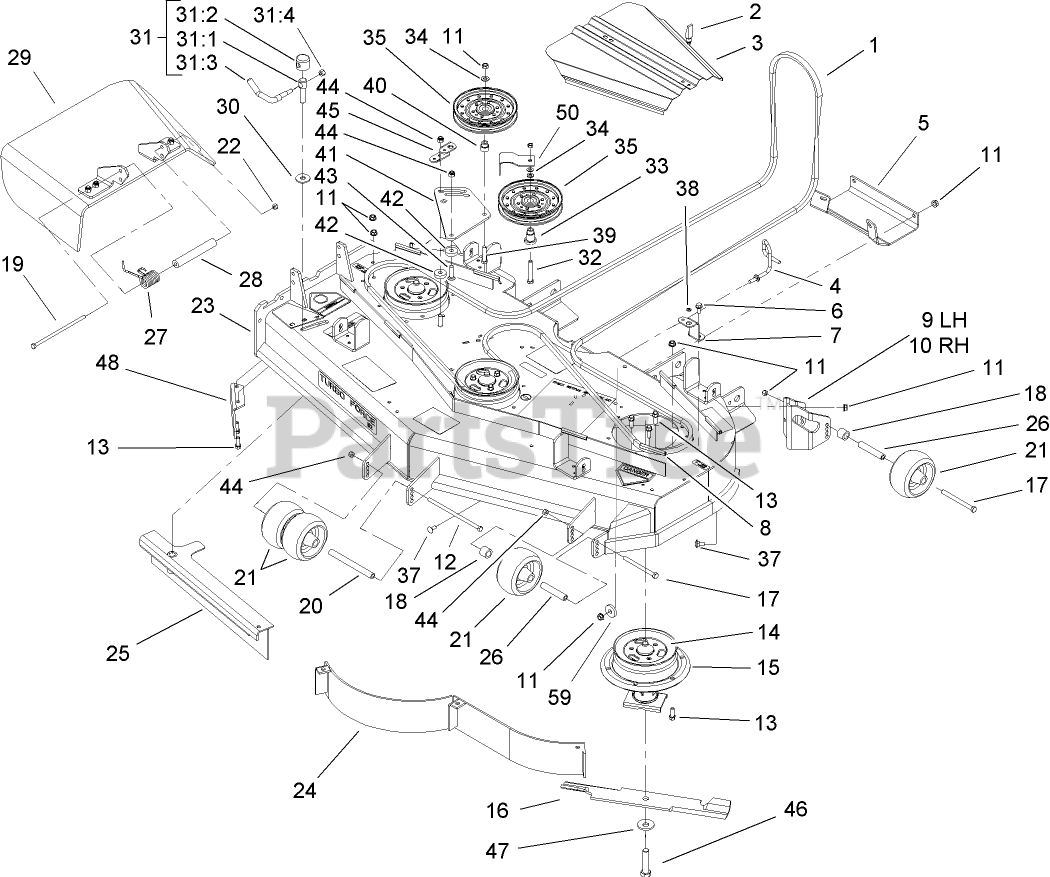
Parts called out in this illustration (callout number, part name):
2	LATCH-SWELL
3	Cover-Belt
4	GUIDE-BELT
5	Plate-Skid
6	SCREW-HWHTF
7	Bracket-Cover
8	STRIP-SEAL
9	MOUNT-WHEEL, LH
10	MOUNT-WHEEL, RH
11	NUT-HHF, WHIZ
12	SCREW-HH
13	SCREW-HWH
14	Pulley
15	Spindle ASM
16	BLADE-18IN, HI FLOW
17	SCREW-HH
18	TUBE-SPACER
19	SCREW-HH
20	SPACER-WHEEL
21	ROLLER-SCALP, ANTI
22	NUT-LOCK, NI
23	DECK ASM
26	TUBE-SPANNER
27	SPRING-TORSION
28	SPACER
29	Rubber Deflector ASM
30	WASHER-PLASTIC
31	Lever ASM
31:1	Screw-Lock
31:2	Cap-Lock
31:3	Lever-Lock
31:4	NUT-LOCK, NI
32	SCREW-HH
33	MOUNT-PULLEY
34	WASHER-FLAT
35	Idler-Flat
37	SCREW-CARR
38	WASHER
39	SCREW-HH
40	BUSHING-IDLER
41	Plate-Idler
42	Spacer
43	SCREW-CARR
44	NUT-LOCK, NI
45	Bracket-Cover, Belt
46	Screw-Cap
47	Washer-Blade Bolt, Heavy
48	BAFFLE-DISCHARGE
50	GUIDE-BELT
59	WASHER
